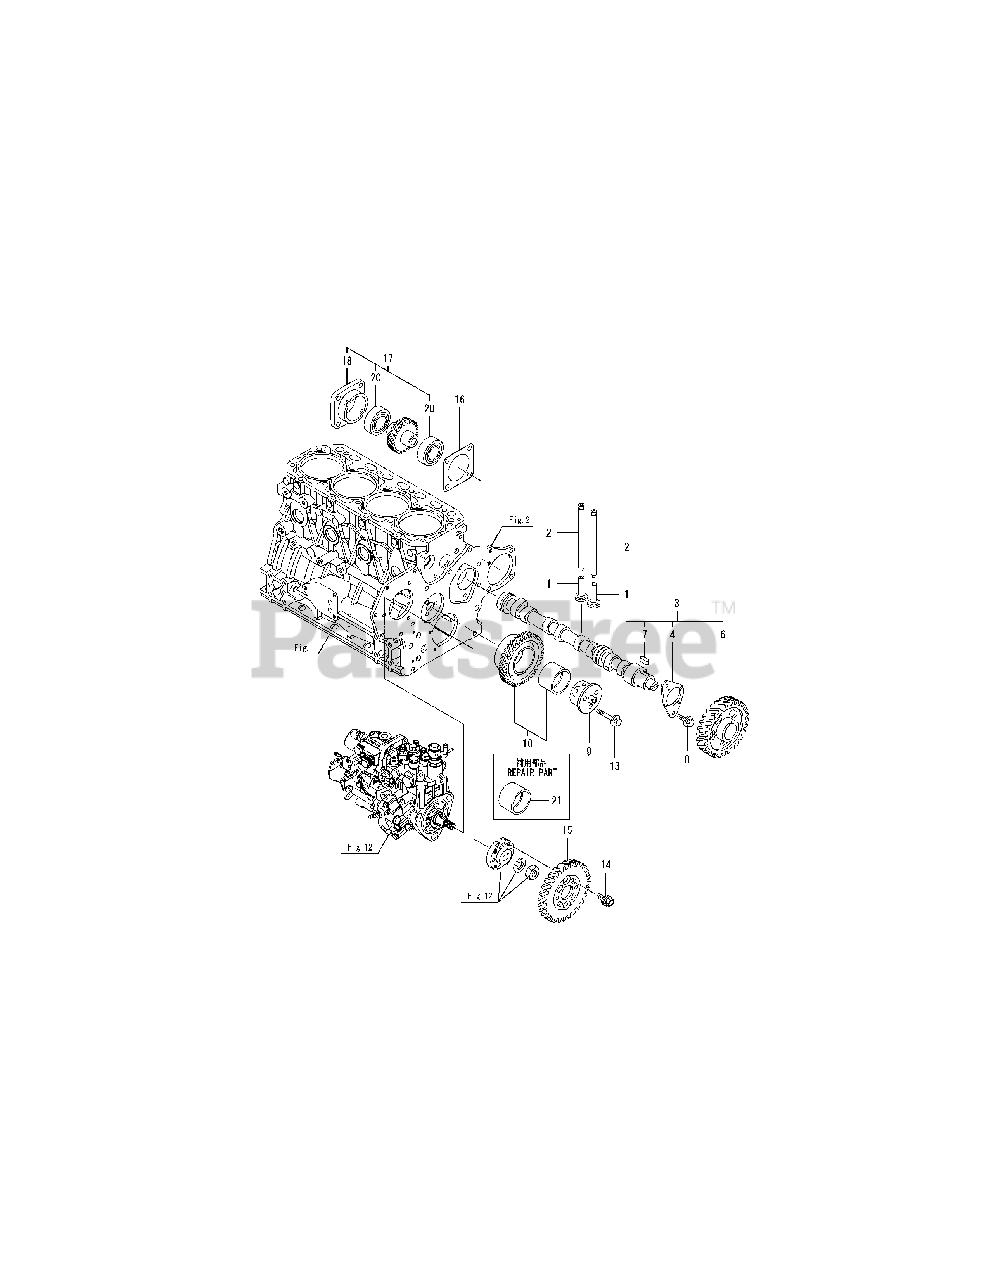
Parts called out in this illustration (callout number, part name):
6	GEAR, CAMSHAFT
8	BOLT 8X 14 PLATED
10	GEAR ASSY, IDLE
13	BOLT M 8X 40 PLATED
17	DRIVE ASSY, PUMP
21	BUSH, IDLE GEAR
